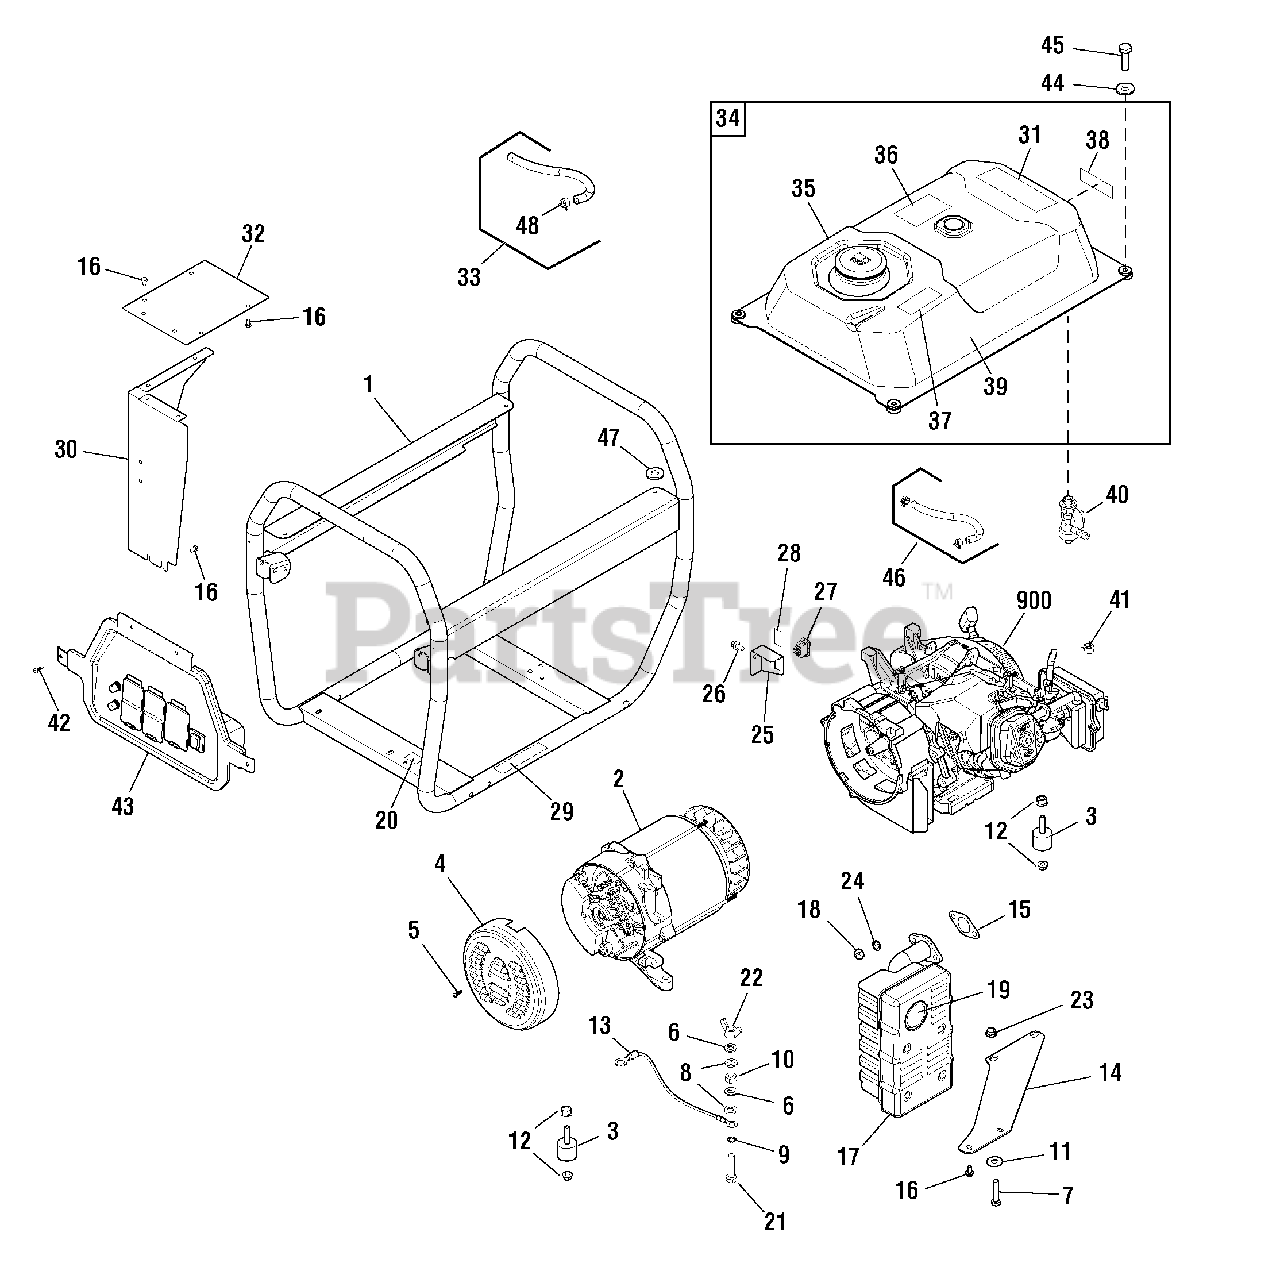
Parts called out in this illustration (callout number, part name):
1	CRADLE
2	ALTERNATOR
3	MOUNT-VIBRATION
4	COVER-REAR BEARING
6	* WASHER, Lock, 1/4
7	* CAPSCREW, Hex Head, M10-1.5 x 45
8	* WASHER, Flat, M6
10	* NUT, Hex, M6-1.0
11	WASHER
16	* CAPSCREW, Hex Head, M6-1.0 x 10
18	* NUT, Hex, M8-1.25
21	* CAPSCREW, Hex Head, M6-1.0 x 25
23	* NUT, Lock, M10
24	* WASHER, Lock, 3/8
26	* SCREW, Flange, M8-10
27	SWITCH-ROCKER
43	PANEL-CONTROL
46	KIT-FUEL HOSE
48	CLAMP
900	** ENGINE
